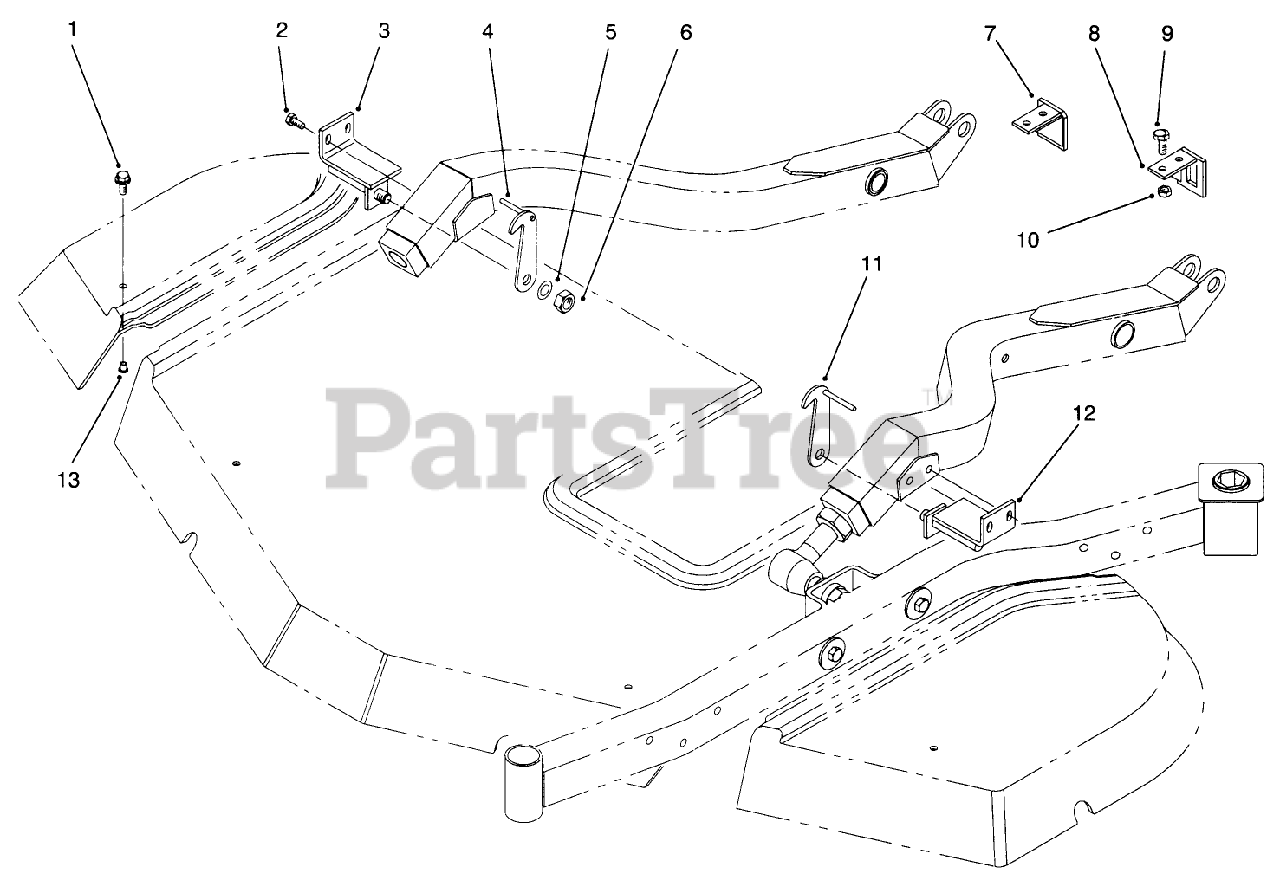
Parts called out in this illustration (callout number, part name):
1	SCREW-HHF
2	SCREW-HWH
3	Bracket-Latch, RH
4	Retainer-Deck, RH
5	WASHER-SPRING
6	5/8-18 LOCK NUT
7	Bracket-Deck, RH
8	Bracket-Deck, LH
9	SCREW-HH
10	NUT-LOCK, SIDE
11	Retainer-Deck, LH
12	Bracket-Latch, LH
13	NUT-INSERT
